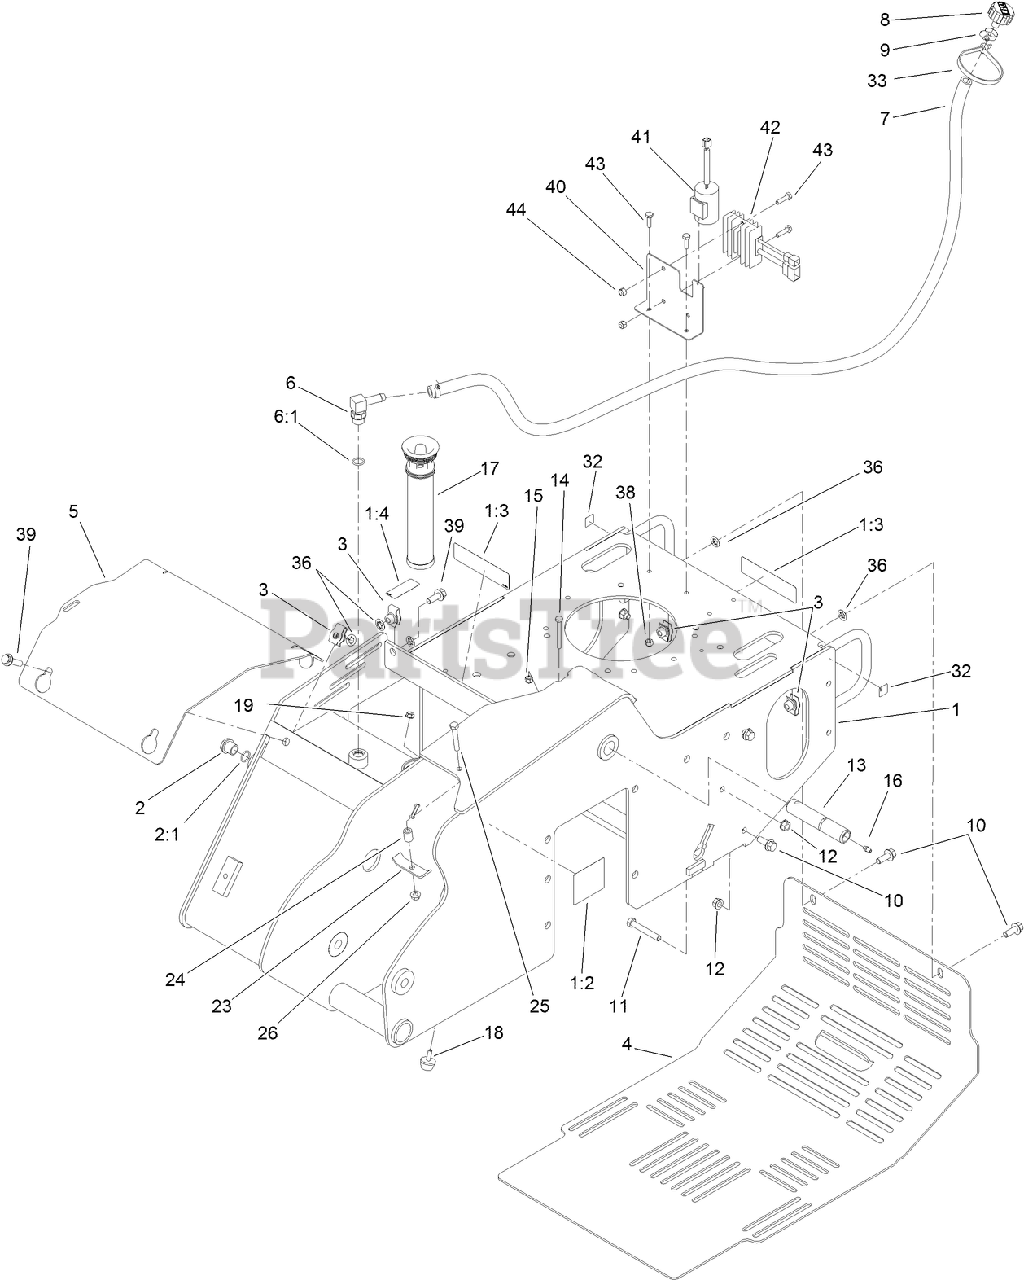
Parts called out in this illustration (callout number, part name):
1	MAIN FRAME ASM
1:2	DECAL-WARNING
1:3	DECAL-DANGER
1:4	DECAL-OIL, HYD
2	SIGHT GLASS ASM
2:1	O-RING
3	Nut-Tinnerman
4	COVER-REAR
5	PLATE-COVER, FRONT
6	FITTING-ELB 90
6:1	O-RING
7	HOSE-BREATHER
8	BREATHER
9	CLAMP-HOSE
10	SCREW-HHF
11	SCREW-HH
12	NUT-FLANGE
13	PIN-PIVOT
14	SCREW-HH
15	NUT-LOCK, NI
16	FITTING-GREASE
17	IN-TANK FILTER ASM
18	BUMPER
19	NUT-HF
23	BRACKET-CLAMP
24	SPACER
25	SCREW-HH
26	NUT-HF
32	DECAL-POINT, LIFT
33	TIE-CABLE
36	NUT-PUSH
38	NUT-LOCK, NI
39	SCREW-HHF
40	BRACKET-ELECTRICAL
41	CONDENSER (F/W ENGINE)
42	REGULATOR (F/W ENGINE)
43	SCREW-HH
44	NUT-LOCK, NI
